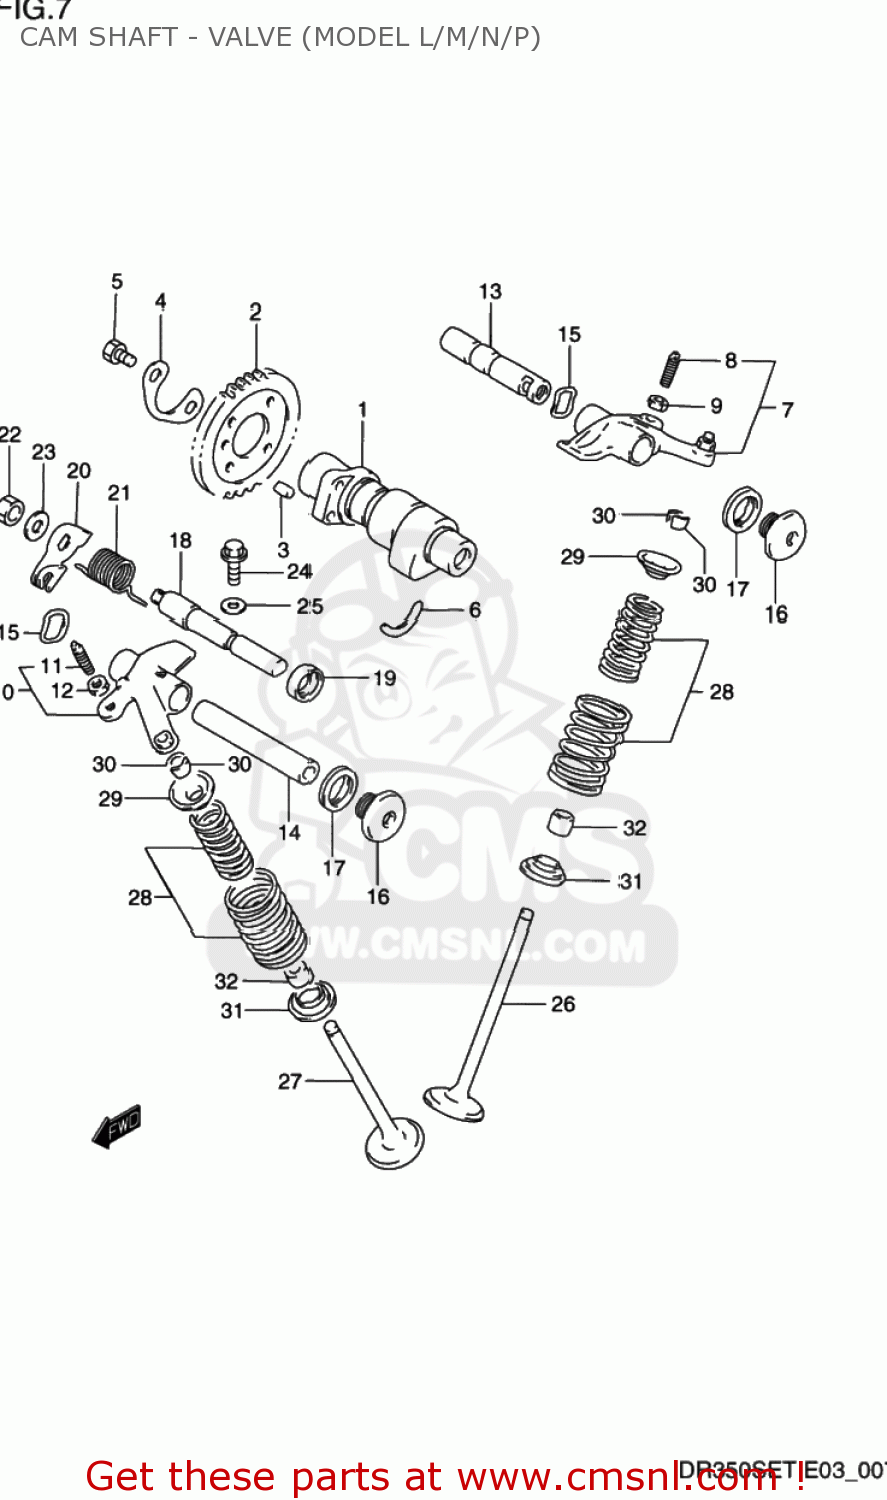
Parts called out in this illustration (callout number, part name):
1	CAMSHAFT
2	SPROCKET,CAMSHAFT INTAKE
3	PIN(5X8)
4	WASHER,SPROCKET
5	BOLT(6X10.5)
6	C RING
7	ARM,VALVE ROCKER INTAKE
8	SCREW,TAPPET ADJUSTING
9	NUT,ADJUSTING
10	ARM,VALVE ROCKER EXHAUST
11	SCREW,TAPPET ADJUSTING
12	NUT,ADJUSTING
13	SHAFT,VALVE ROCKER ARM INTAKE
14	SHAFT,VALVE ROCKER ARM EXHAUST
15	WASHER
16	PLUG,14X12
17	GASKET(14X19.2X2) (NAS)
18	SHAFT,DECOMP
19	SEAL,OIL(10X17X6)
20	LEVER,DECOMPRESSION SHAFT
21	SPRING
22	NUT 8MM
23	WASHER
24	BOLT
25	GASKET(6.4X11.5X0.8) (NAS)
26	VALVE,INTAKE
27	VALVE,EXHAUST
28	SPRING SET,VALVE
29	RETAINER,VALVE SPRING
30	COTTER VALVE
31	SEAT,VALVE SPRING
32	SEAL,OIL(5X10X9.7)
